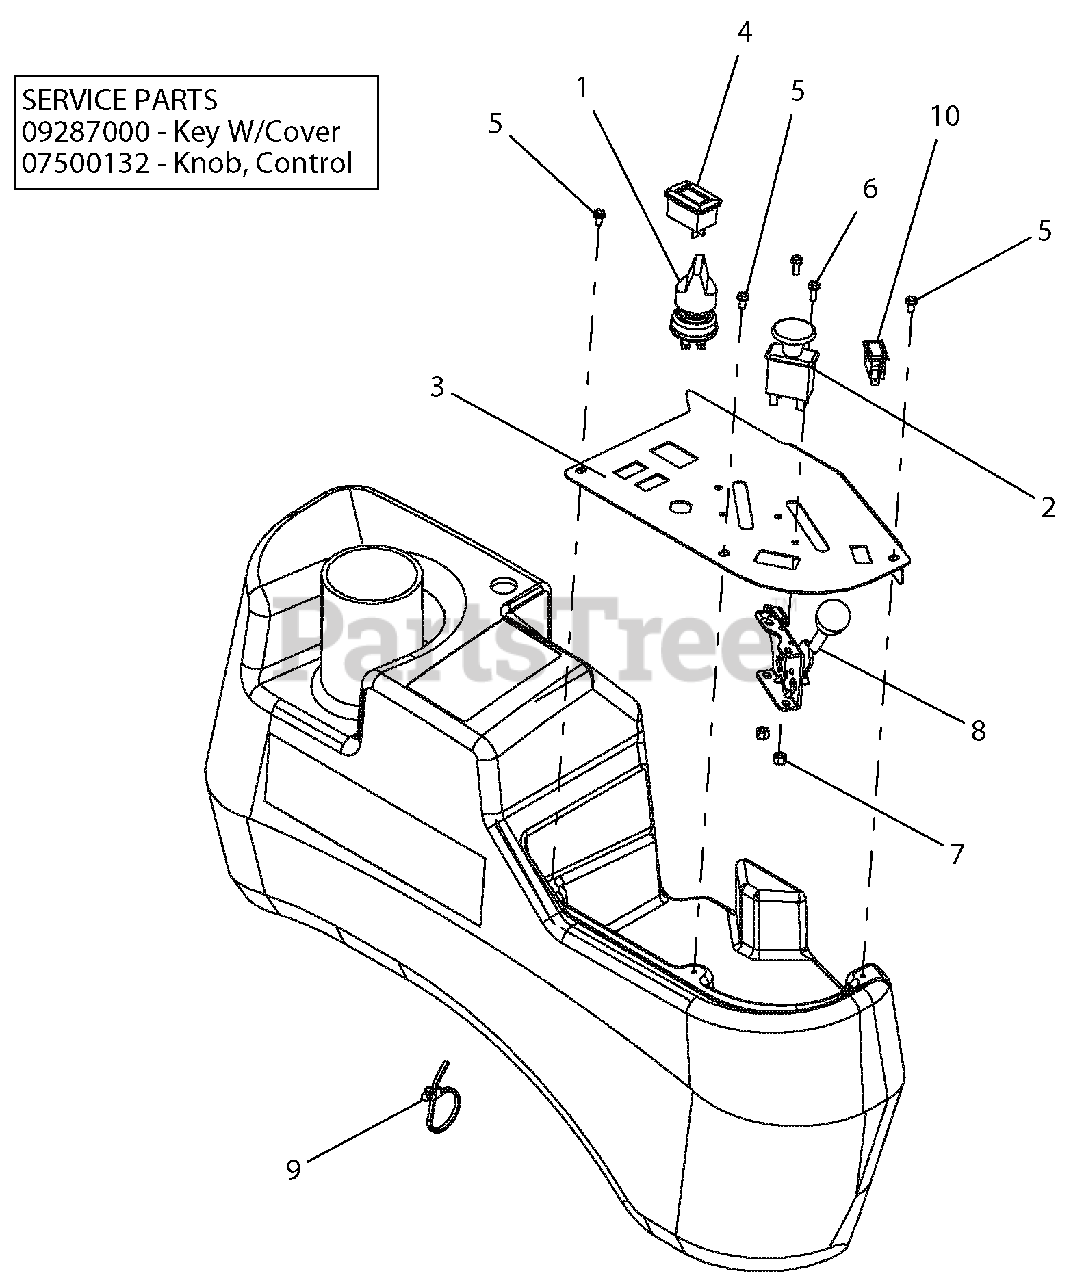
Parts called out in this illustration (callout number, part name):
1	SWITCH, IGNITION
2	SWITCH, CLUTCH
3	PANEL, CONTROL-BLACK
4	METER, HOUR W/MAINTENANCE
5	SCR-MCH 10-24X.38 HWHSTAINLESS
6	@SCR-MCH 10-24X.50 HWH YWZC
7	NUT-LK-NYL #10-24 YWZC
8	CABLE, PRO-CONTROL THROTTLE
9	CABLE TIE W/ TREE (.25 HOLE)
10	LIGHT, INDICATOR
